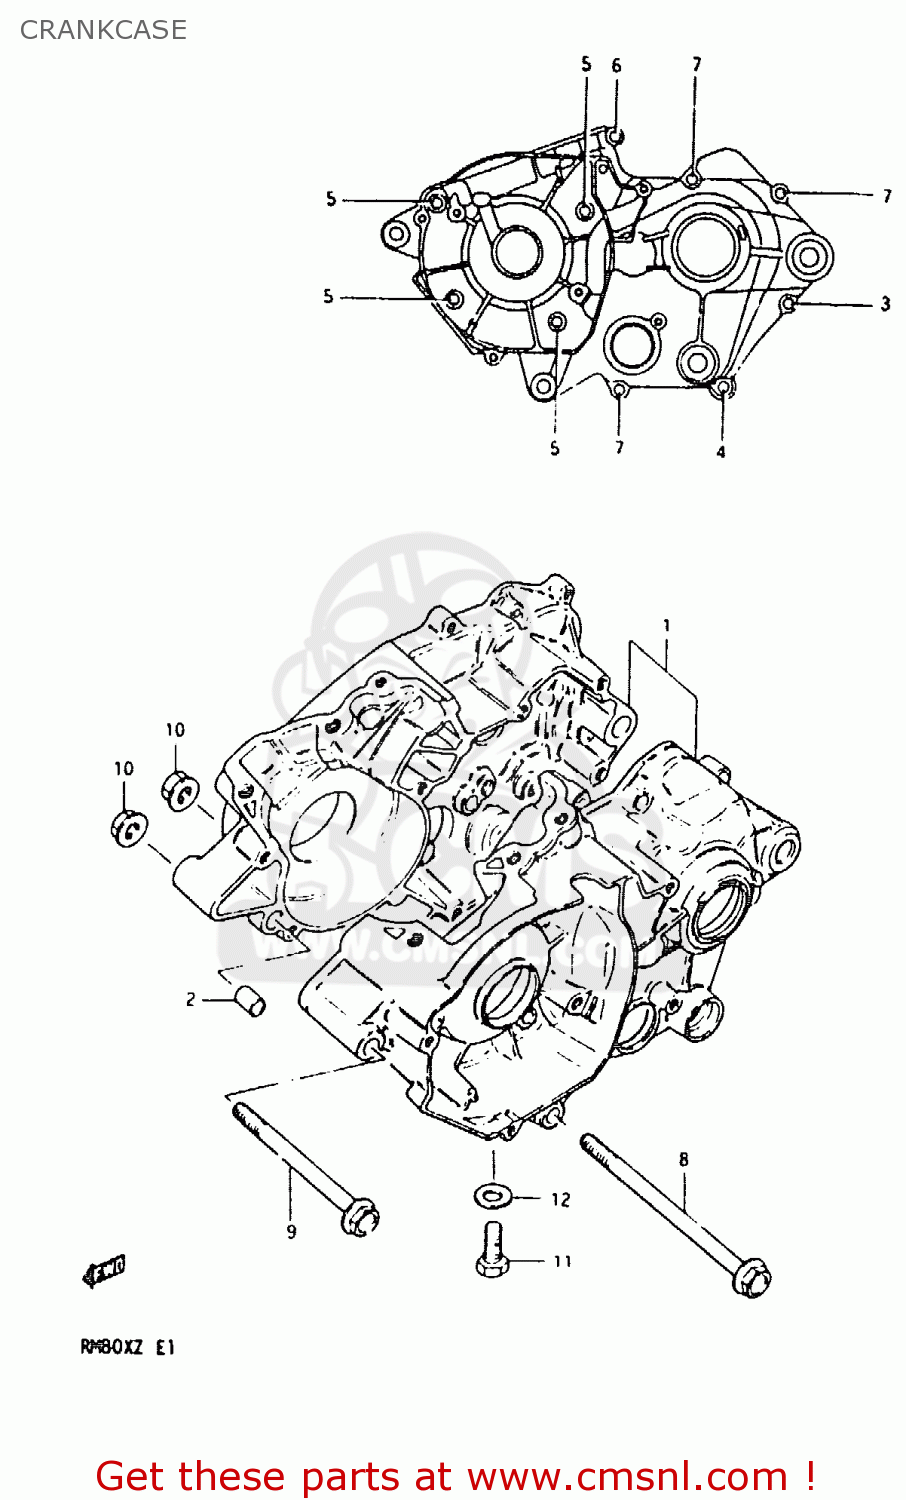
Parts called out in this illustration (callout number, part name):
1	CRANKCASE ASSEMBLY
2	PIN
3	SCREW
4	SCREW (6X45)
5	SCREW
6	SCREW (6X35)
7	SCREW
8	BOLT
9	BOLT(8X95)
10	NUT
11	BOLT
12	GASKET 8.2X14X1 (NAS)
